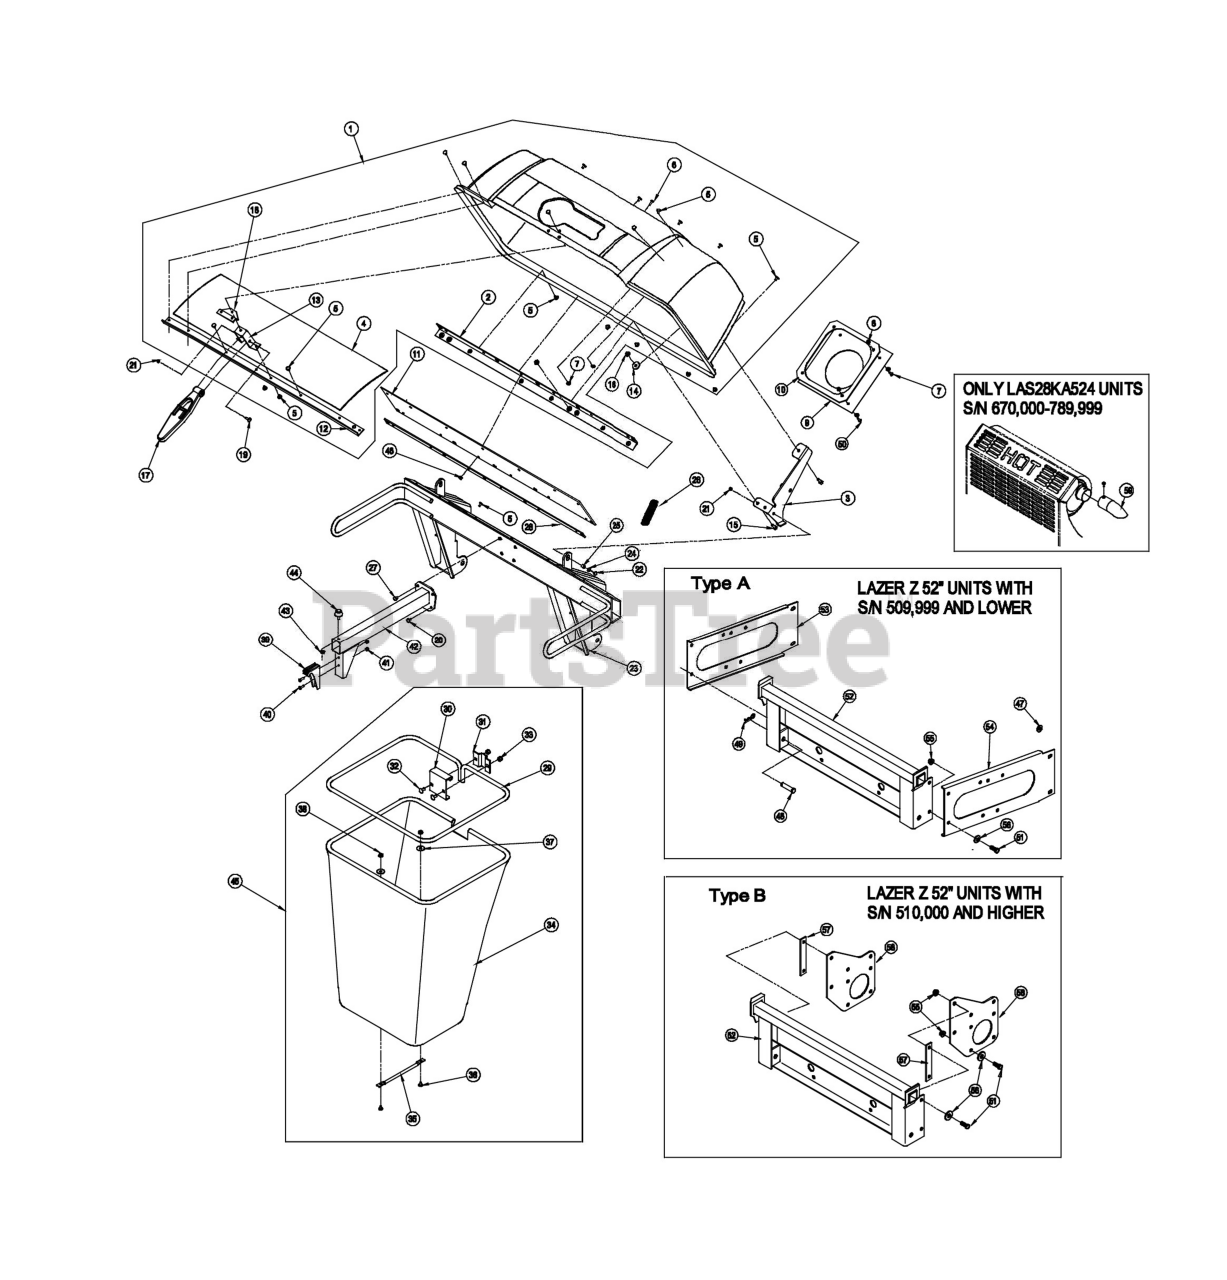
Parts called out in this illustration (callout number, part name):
1	ASM, HOOD
2	STIFFENER-BAGGER, TOP
4	SCREEN-BAGGER
5	RIVET-BLIND
6	SCREW-HEAD, TRUSS
7	WASHER-FLAT
8	NUT-LOCK, NI
9	SEAL-CHUTE
10	CLAMP-SEAL
11	SEAL-HOOD
12	SUPPORT-SCREEN
13	ANCHOR-LATCH
15	SCREW-HH
18	REINFORCEMENT-LATCH
19	SCREW-HH
20	SCREW-HSBH
21	NUT-LOCK, NI
22	SCREW-HH
23	UPRIGHT-BAGGER
24	WASHER-FLAT
26	SPRING-EXTENSION
27	SCREW-HH
28	PLATE-BACKING
29	FRAME-BAG
30	HANGER-BAG
32	BOLT-CARR
33	NUT-LOCK, NI
35	HANDLE-BAG
36	BOLT-CARR
38	NUT-LOCK, NI
40	SCREW-PPH
42	SUPPORT-BAG
45	BAG AND FRAME ASM
46	NUT-LOCK, SIDE
47	SPACER
48	PIN-CLEVIS
49	PIN-COTTER
50	SCREW-PPH
51	SCREW-HH
52	MOUNT-BAGGER
53	BRACKET-FRAME, LH
54	BRACKET-FRAME, RH
55	NUT-HHF, WHIZ
56	WASHER-BELLEVILLE
58	PLATE-MOUNT, BAGGER
59	TUBE,EXHAUST DEFLECTOR
